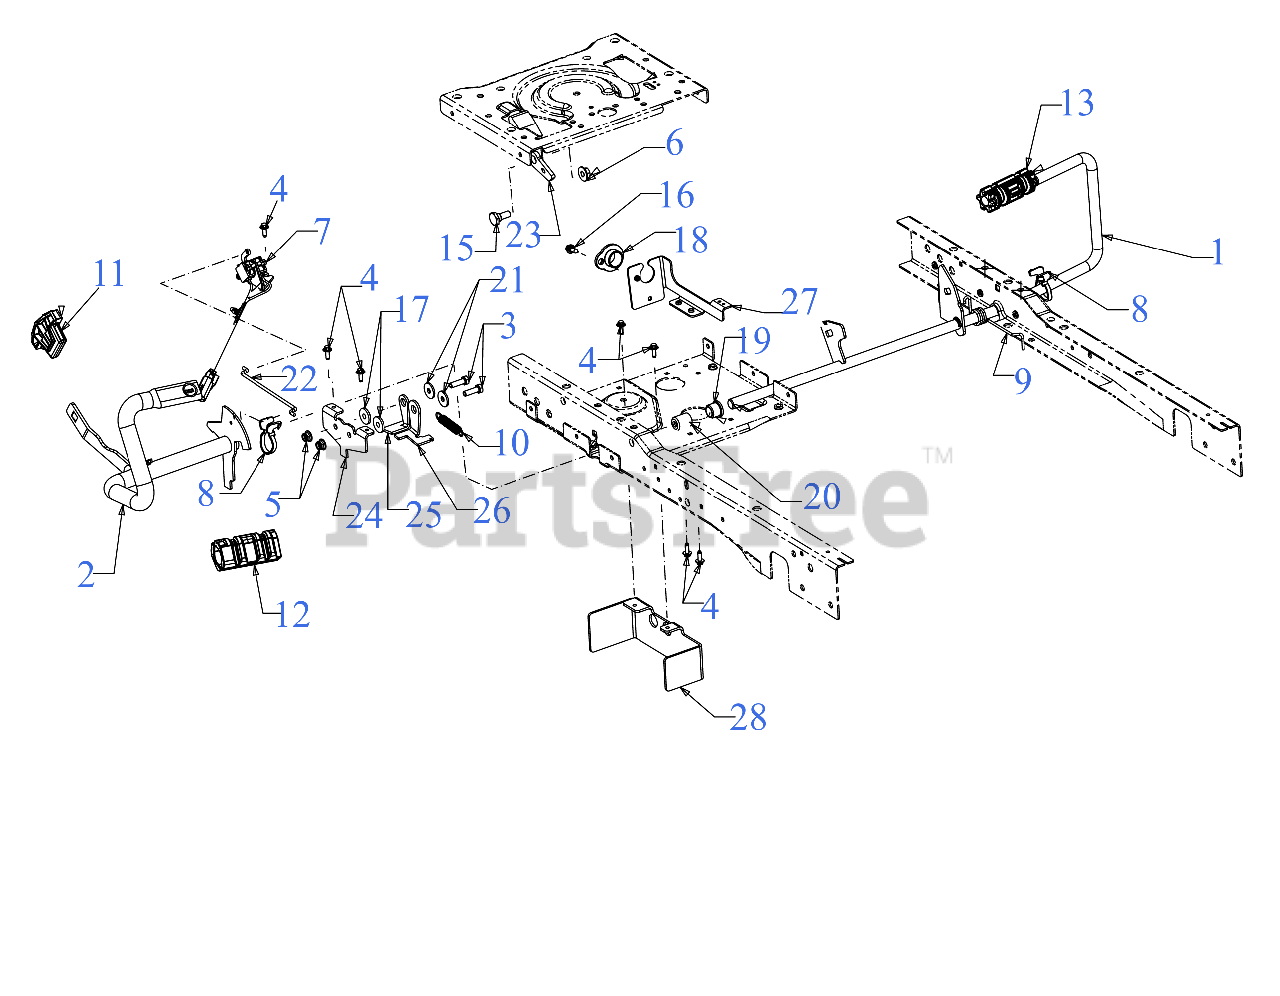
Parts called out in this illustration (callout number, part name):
1	BRAKE PEDAL ASSEMBLY
2	FWD/REV PEDAL ASSEMBLY
3	SCREW 5/16-18 x 1.0 GR5
4	SCREW M6-1 x .625
5	FLANGE LOCK NUT 5/16-18
6	FLANGE LOCK NUT
7	THROTTLE SENSOR (DUEL CLIP)
9	TORSION SPRING .725
10	SPRING-EXT .51"DIA x 2.85"LG
11	REVERSE PEDAL PAD
12	FORWARD PEDAL PAD
13	BRAKE PEDAL PAD
15	SHOULDER SCREW
16	SHOULDER SCREW
17	SHOULDER SPACER (.315" x .50" x.14")
18	FLANGE BEARING
19	FLANGE BEARING .63X.84X.71
20	PLASTIC SLEEVE BEARING
21	THRUST BEARING (.323" x .985" x .1")
22	SWITCH ROD
23	CRUISE LATCH
24	NEUTRAL RETURN BRACKET
25	FORWARD RETURN BRACKET
26	REVERSE RETURN BRACKET
27	BRAKE SWITCH BRACKET
28	RETURN COVER PLATE
